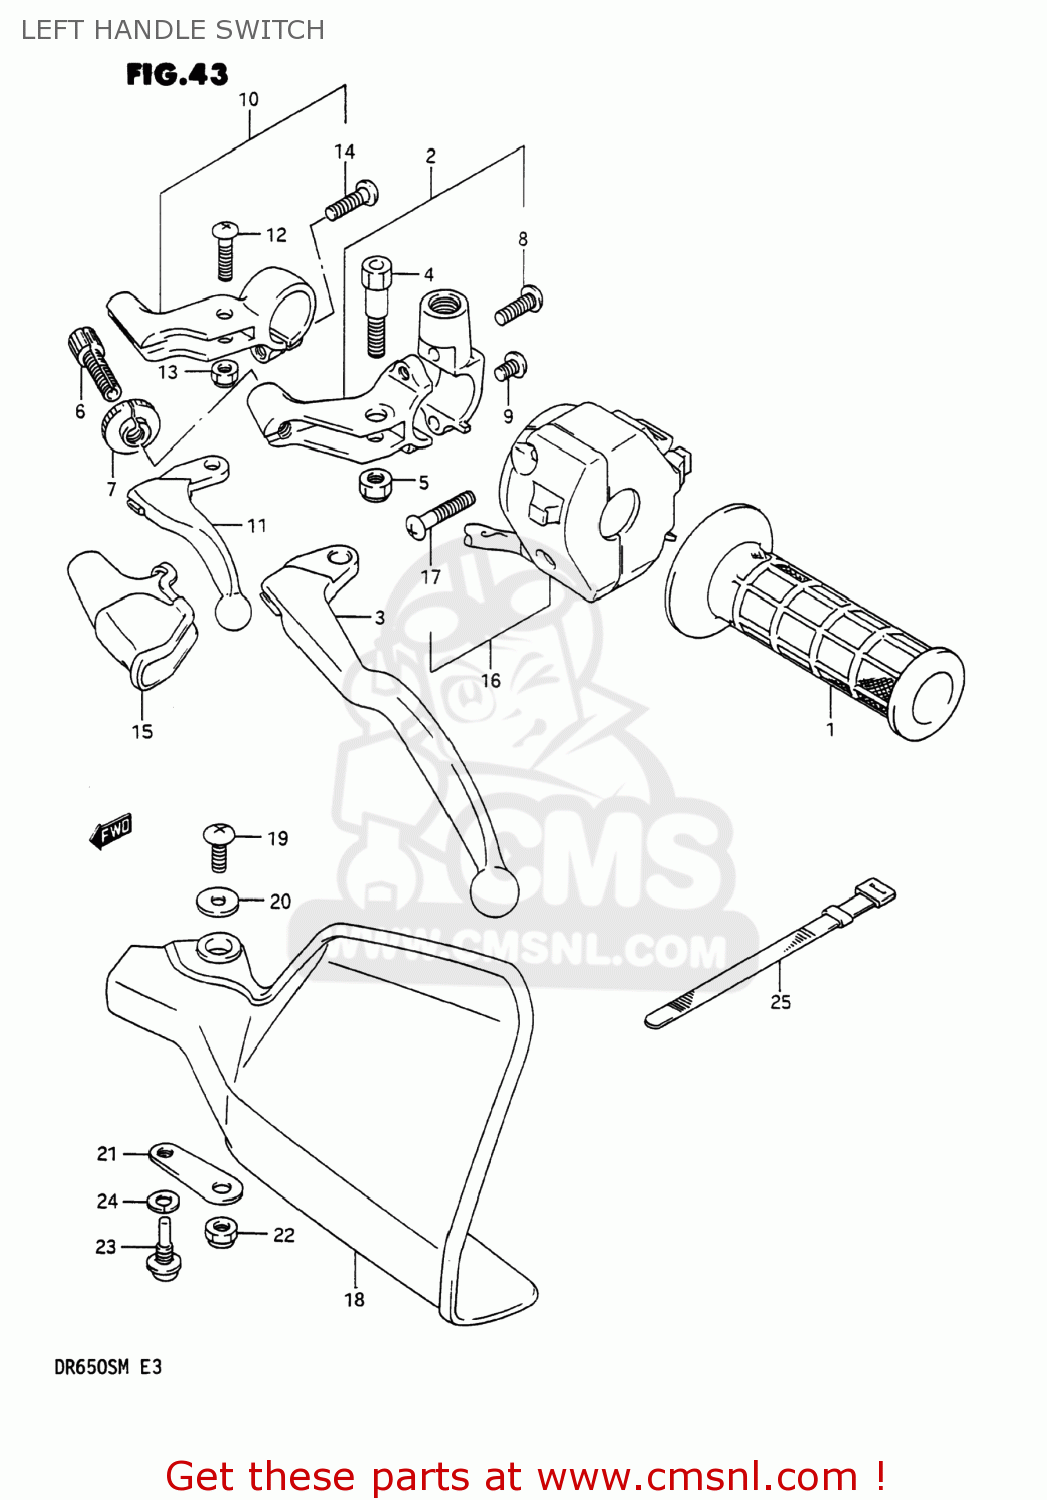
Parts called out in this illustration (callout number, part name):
1	GRIP,L
2	LEVER ASSEMBLY,CLUTCH
3	LEVER,CLUTCH
4	BOLT,LEVER SET
5	NUT 6MM
6	ADJUSTER,CABLE
7	NUT,LOCK
8	SCREW
9	SCREW(5X25)
10	LEVER ASSEMBLY,DECOMPRESSION
11	LEVER,DECOMP
12	BOLT,LEVER PIVOT
13	NUT
14	SCREW
15	COVER,DECOMP LEVER DUST
16	SWITCH ASSEMBLY,HANDLE,LEFT
17	SCREW
18	COVER,KNUCKLE,LEFT
19	SCREW(5X10)
20	WASHER (5.5X16X1.2)
21	PLATE,KNUCKLE COVER,L LWR
22	NUT 6MM
23	SCREW
24	WASHER,LOCK
25	CLAMP(L:120)
